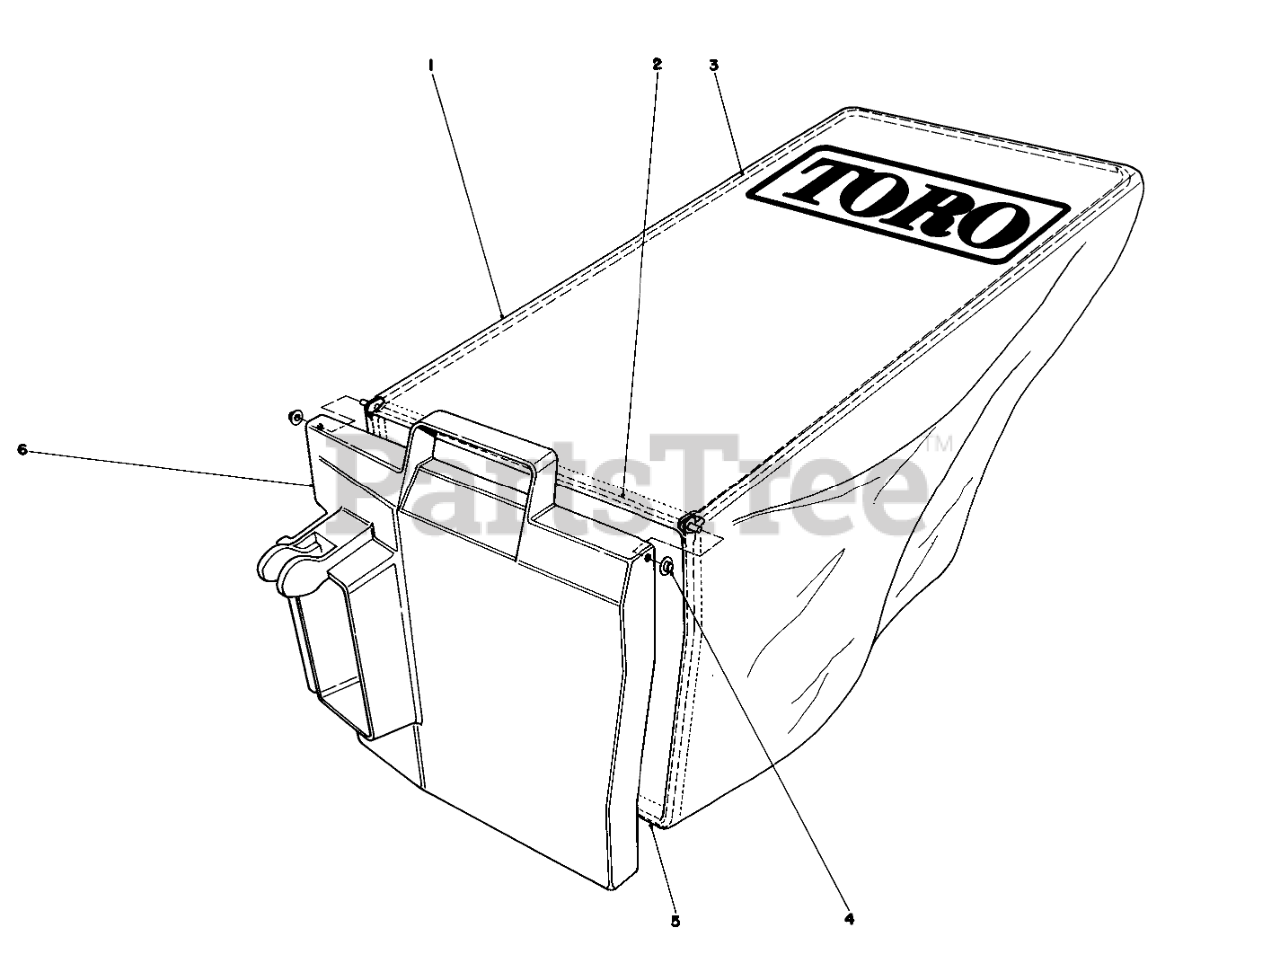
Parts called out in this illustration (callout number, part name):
1	Bag
2	HINGE PIN
3	BAG FRAME-UPPER
4	NUT-PUSH
5	Frame Bag
6	Door-Bag
